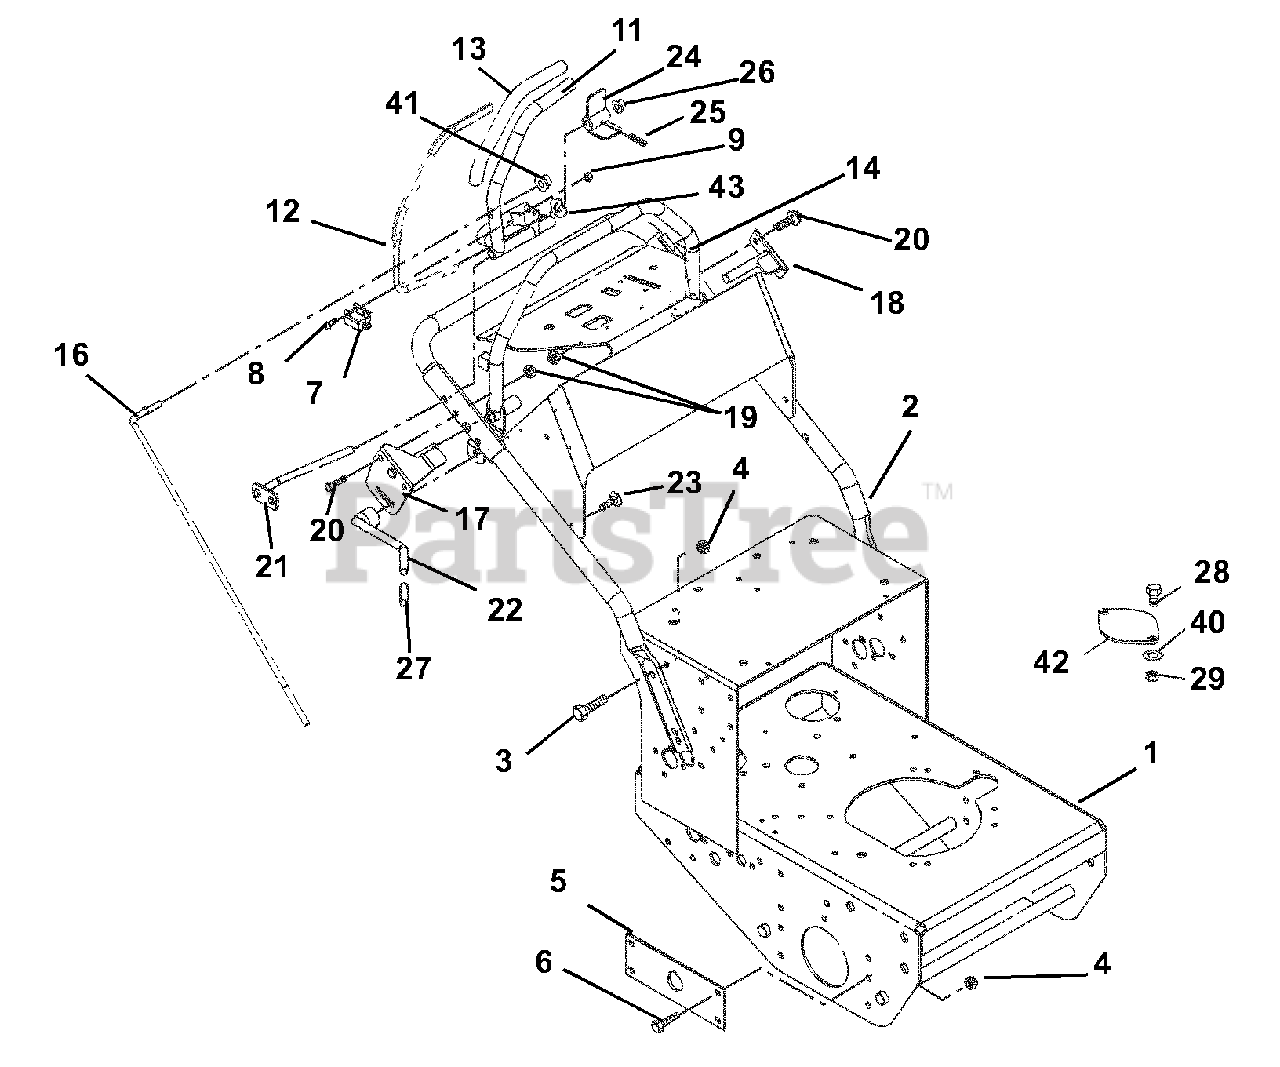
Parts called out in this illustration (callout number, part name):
1	KIT-FRAME W/DECALS
2	KIT-HANDLEBAR/DECAL GR13/15-PS
3	@BLT-HEX .38-16X1.00 GR5 YWZC
4	@NUT-LK-NYL .38-16 YWZC
5	PLATE, SUPPORT
6	@BLT-HEX .38-16X1.00 GR5 YWZC
7	SWITCH- SINGLE POLE N.O.
8	@SCR-MCH 10-24X.75 HWH YWZC
9	@NUT-LK-NYL 10-24 W/INSRT YWZC
11	WMT-LEVER-RH SPEED CONTROL-GR
11	WMT-LEVER-LH SPEED CONTROL-GR
12	LEVER - OPERATOR PRESENCE
13	GRIP - HANDLEBAR
14	WMT - SPEED CONTROL STOP
15	RG-RTNG-EXT .375X.010
16	ROD - STEERING
17	WMT-CONTROL STOP LIMITER-RH
17	WMT - CONTROL STOP LIMITER -RH
18	WMT-CONTROL STOP LIMITER-LH
19	@NUT-LK-TOP-FLG .31-18 YWZC
20	@BLT-HEX .31-18X1.75 GR5 YWZC
21	WMT - SPEED CONTROL PIVOT - RH
21	WMT - SPEED CONTROL PIVOT - LH
22	LEVER - CONTROL STOP LOCK
23	BLT-RDHDSQSHK.31-18X.75 GR2 YW
23	@BLT-RDHDSQNK .38-16X.75 G5YZ
24	ACTUATOR - SWITCH
25	PIN-ROLL .125X.75
26	NUT-PUSH .312
27	GRIP,HAND CLUTCH LEVER
28	@BLT-HEX .38-16X.75 GR5 YWZC
29	@NUT-LK-TOP-FLG .38-16 YWZC
40	@WSHR-FL-STL.406X.812X.065 YWZ
41	RG-RTNG-EXT .375X.010
42	PLATE, COVER
43	WAVE WASHER .390X.655X.110
